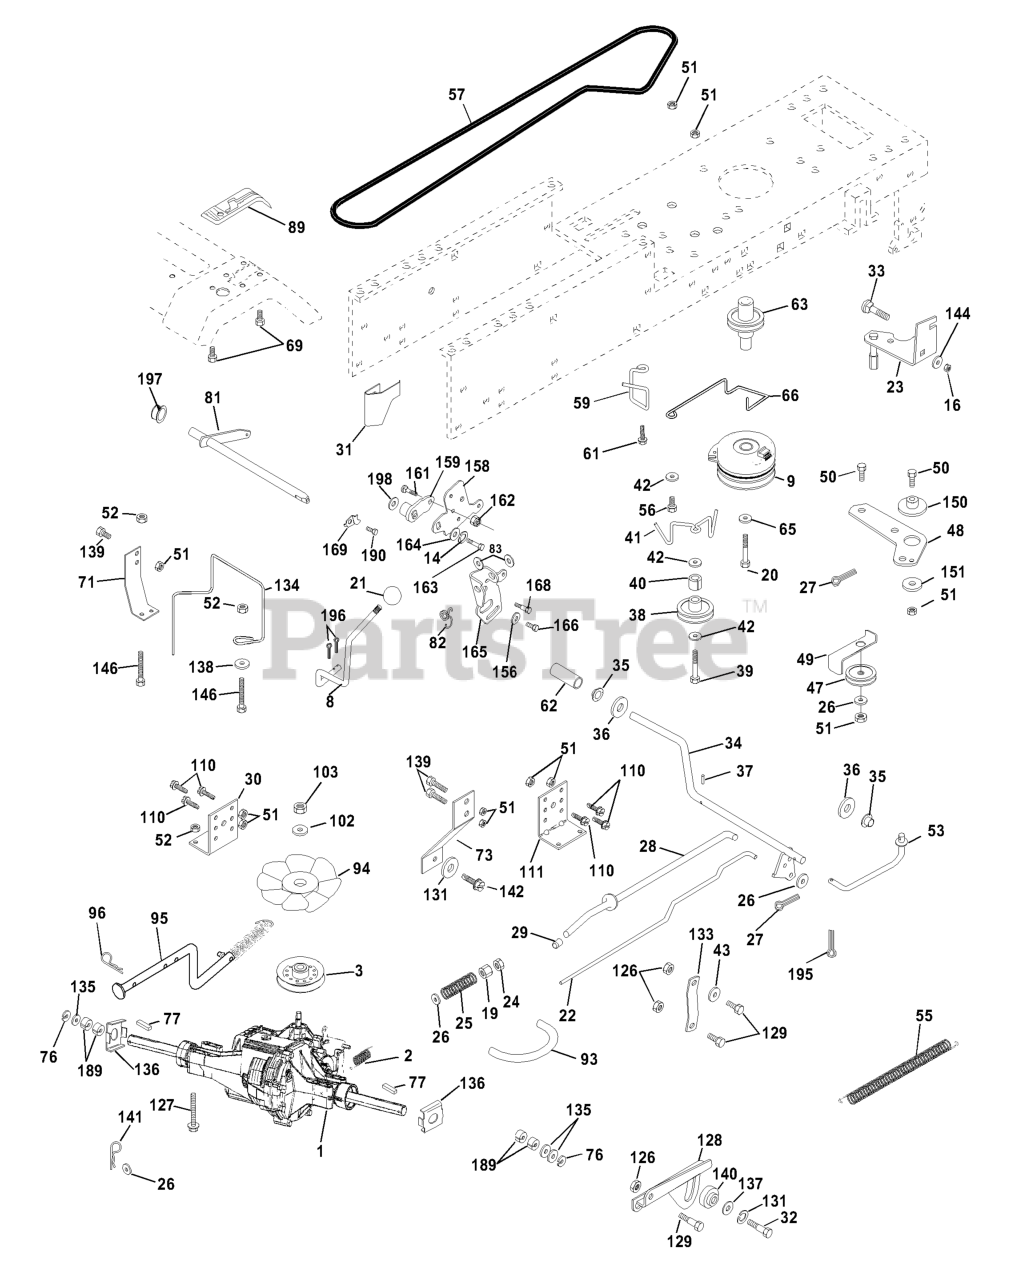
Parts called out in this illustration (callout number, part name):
2	SPRING BRAKE
3	PULLEY, TRANSAXLE
8	ROD SHIFT FENDER
9	ELECTRIC CLUTCH
14	WASHER LOCK
16	NUT LOCK HEX W/INS. 5/16-18UNC
19	NUT LOCK HEX 3/8-16
20	BOLT HEX 7/16-20 X 4-1/4 GA 5
21	KNOB.DELUXE.(PISTOL.GRIP).BLAC
22	Rod, Brake
24	NUT
25	SPRING
26	WASHER
27	PIN
28	ROD
29	PLUNGER CAP
30	BRKT TRANS LH
31	KEEPER BELT LH
32	BOLT
33	BOLT
34	SHAFT, FOOT PEDAL
35	BEARING.NYLON
36	WASHER
37	DRIVE PIN
38	FLAT IDLER PULLEY
39	BOLT
41	KEEPER.BELT.IDLER.FLAT
42	BOLT
43	Washer 11/32 x 5/8 x 12 Ga.
47	IDLER PULLEY
48	BELLCRANK, CLUTCH
49	RETAIN BELT
50	BOLT
51	NUT
52	NUT
53	LINK, CLUTCH LT
55	SPRING, RETURN LT
56	BOLT
59	KEEPER CENTER SPAN
61	SCREW
62	PEDAL COVER T
63	ENGINE PULLEY
65	WASHER
66	BELT KEEPER
69	SCREW.HI-LO.CONSOLE
71	STRAP.TORQUE.LH.HYDRO
73	STRAP.TORQUE.RH.HYDRO
76	E RING HYT
77	SQ KEY STD
81	SHIFT.ASM.CROSS.TAPER
82	SPRING,TORSION
83	WASHER
89	FENDER CONSOLE
93	LINE FUEL HYD 4"
94	FAN 7" HYDRO
95	CONTROL.ASM.BYPASS.HYDRO-3000
96	RETAINER SPRING
103	NUT
110	Bolt, Hex 3/8-16 UNC x 3/4
111	BRKT TRANS RH
127	BOLT HEX FLGHD 5/16-18X 3 GR 5
129	Bolt 5/16-18 UNC
131	Washer Lock 5/16 NDM PLTD
133	LINK, TRANSAXLE
134	BELT GUIDE
136	WASHER.AXLE.FLANGE.HG-3000
137	Washer 11/32 x 3/4 x 12 Ga.
138	Washer 11/32 x 1.25 x 16 Ga.
139	Bolt, Hex 3/8-16 UNC x 3/4
142	Bolt 5/16 x 24 x 1
144	WASHER
146	BOLT
150	BUSHING.BELLCRANK.GRD.DR
151	WASHER
156	WASHER
158	BRACKET
159	HUB
161	BOLT
162	NUT
163	BOLT
164	WASHER
165	RP BRACKET
168	BOLT
169	PLATE FASTENING LT
189	Washer Spacer Axle
190	SCREW
195	Pin Cotter 1/8 x 3/4 Cad Blk D
196	Pin, Cotter 1/8 x 1
197	NYLINER SNAP 5/8" ID
198	WASHER.NYL.7/8IDX.105"HYD CR
